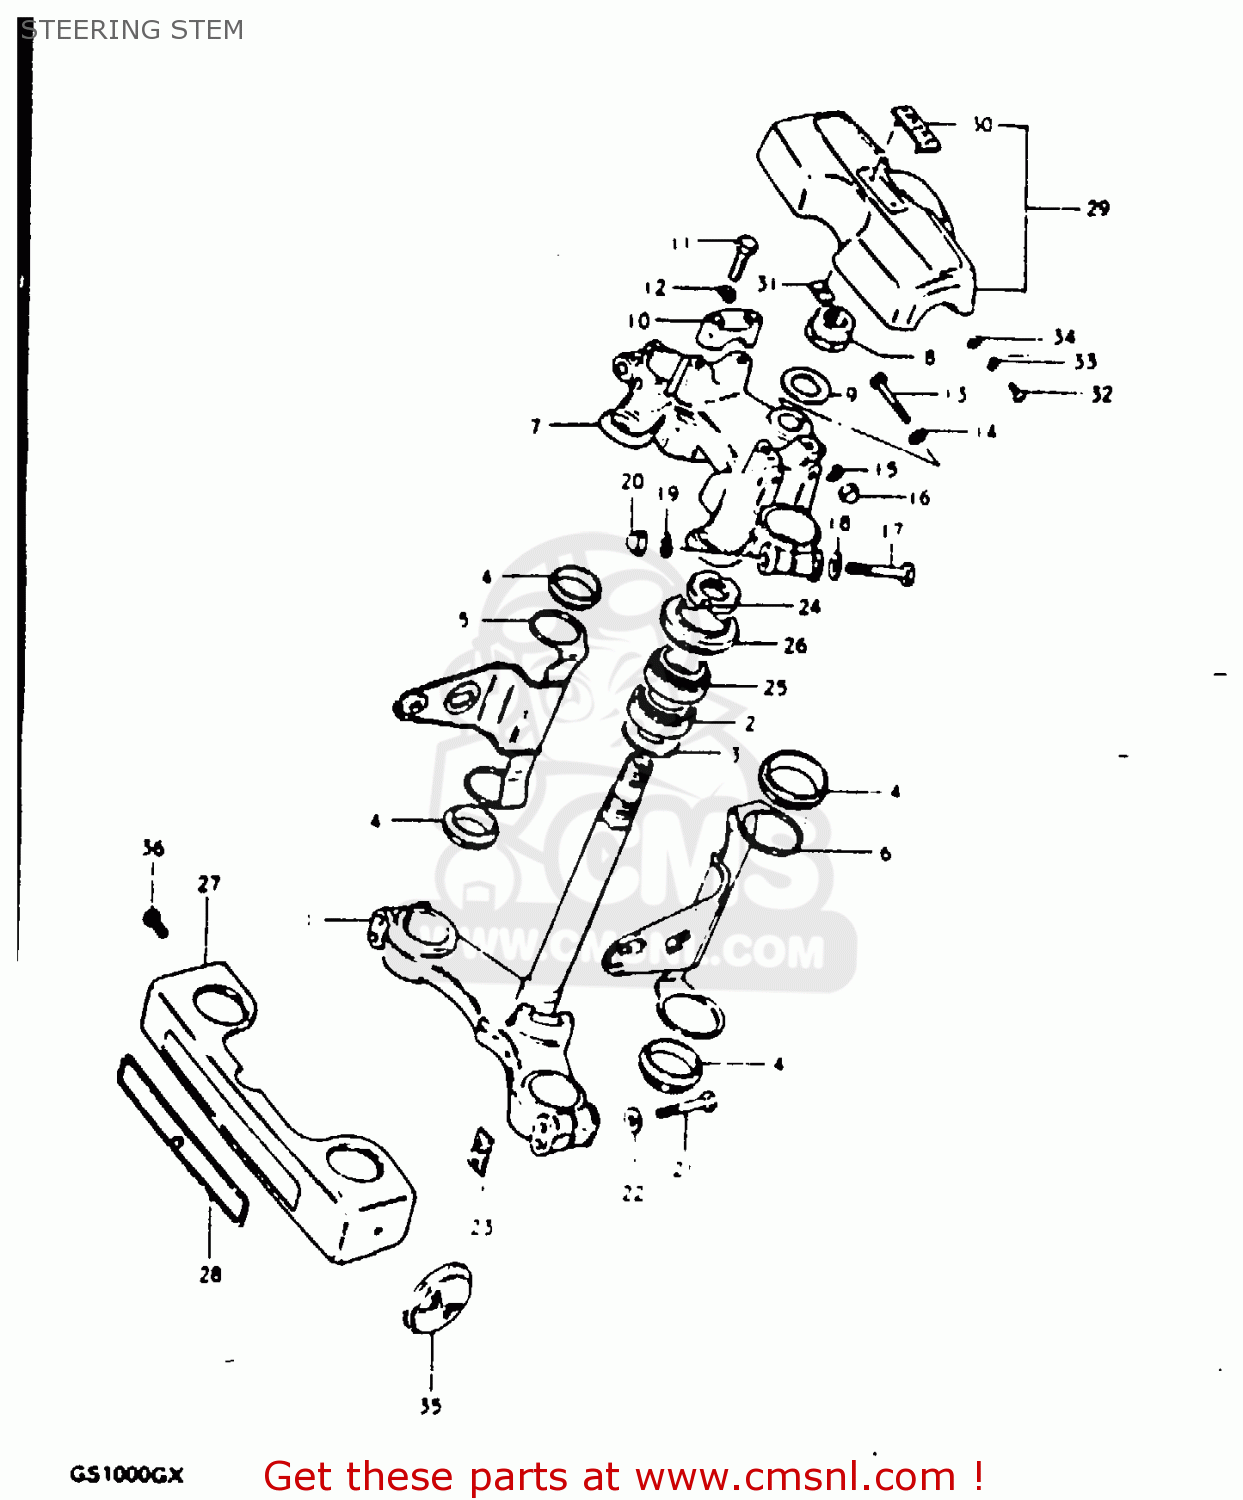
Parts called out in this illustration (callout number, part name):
1	STEM,STEERING
2	BEARING
3	WASHER,THRUST
4	CUSHION,HEADLAMP BRACKET
5	BRACKET,HEADLAMP,RIGHT
6	BRACKET,HEADLAMP,LEFT
7	HEAD,STEERING STEM
8	NUT,FR FORK UPR BRACKET
9	WASHER
10	HOLDER,HANDLE(BLACK)
11	BOLT
12	LOCK WASHER
13	BOLT 8X50
14	WASHER
15	LOCK WASHER
16	NUT
17	BOLT 10X55
18	WASHER
19	LOCK WASHER
20	NUT, LOWER LH
21	BOLT 8X55
22	WASHER
23	NUT,FR FORK INNER TUBE
24	NUT,STEERING STEM(25X44X10)
25	TAPER,ROLLER BEARING
26	DUST SEAL,STEERING,UPPER
27	COVER,FRONT FORK
28	EMBLEM
29	PAD,HANDLEBAR
30	EMBLEM,HANDLE COVER PAD
31	NUT
32	SCREW
33	LOCK WASHER
34	WASHER
35	REFLEX REFLECTOR,RR
